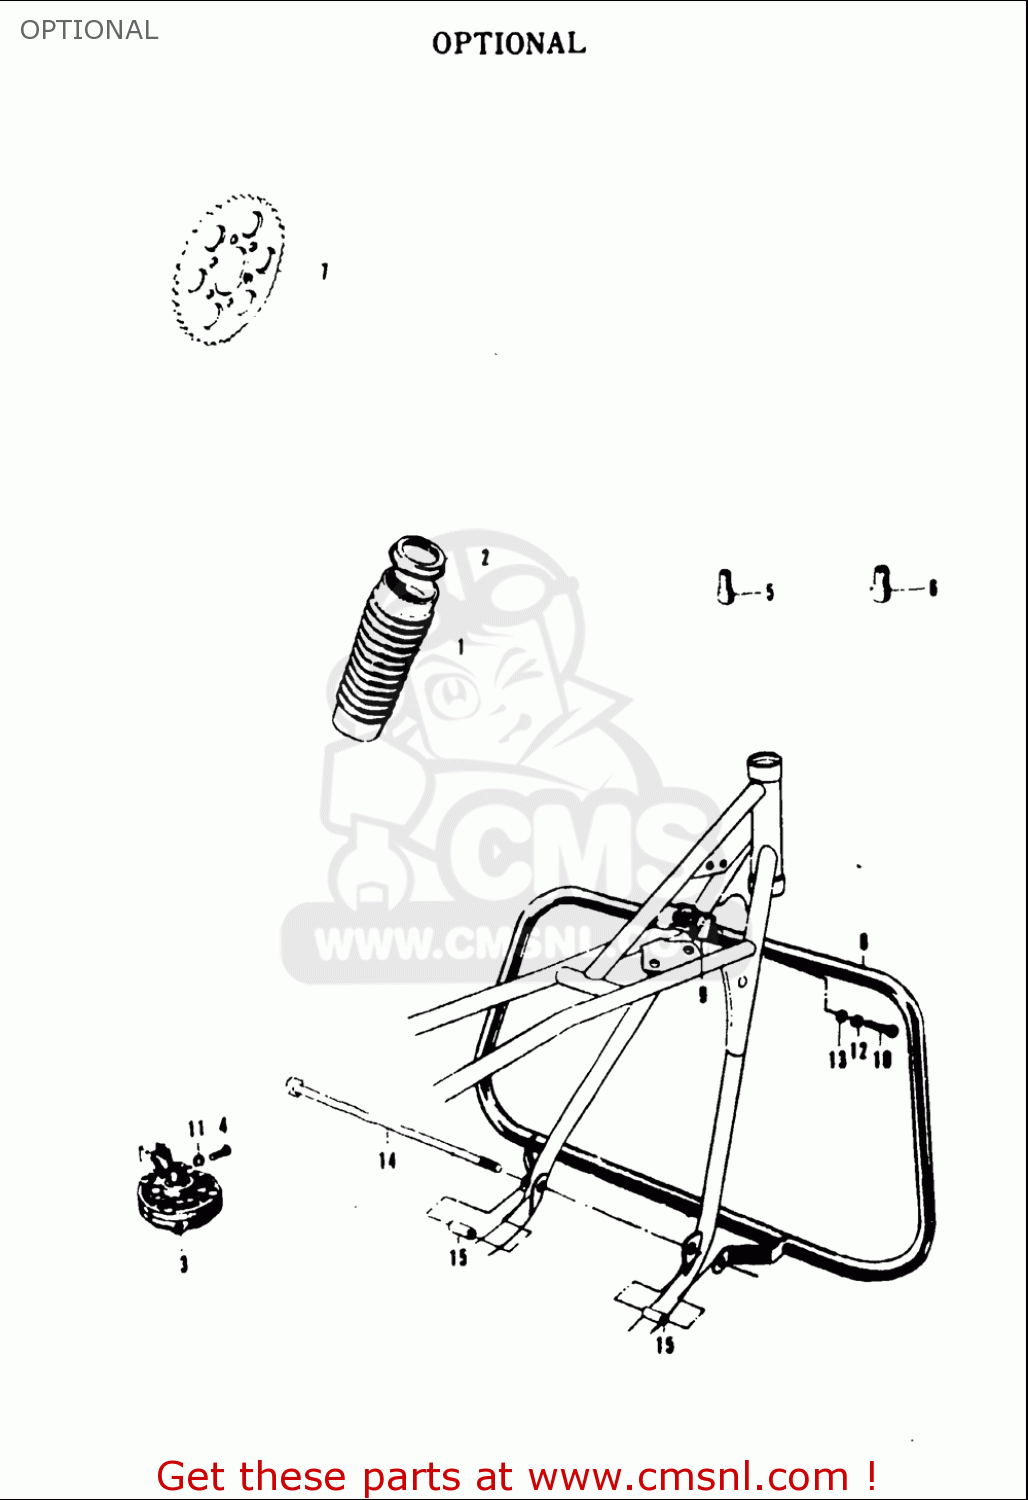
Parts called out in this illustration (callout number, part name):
1	BOOT,SPRING COVER
5	BALANCER,WHEEL (B)
6	BALANCER,WHEEL (30G)
11	WASHER,LOCK
13	WASHER
16	LEVER,TIRE
